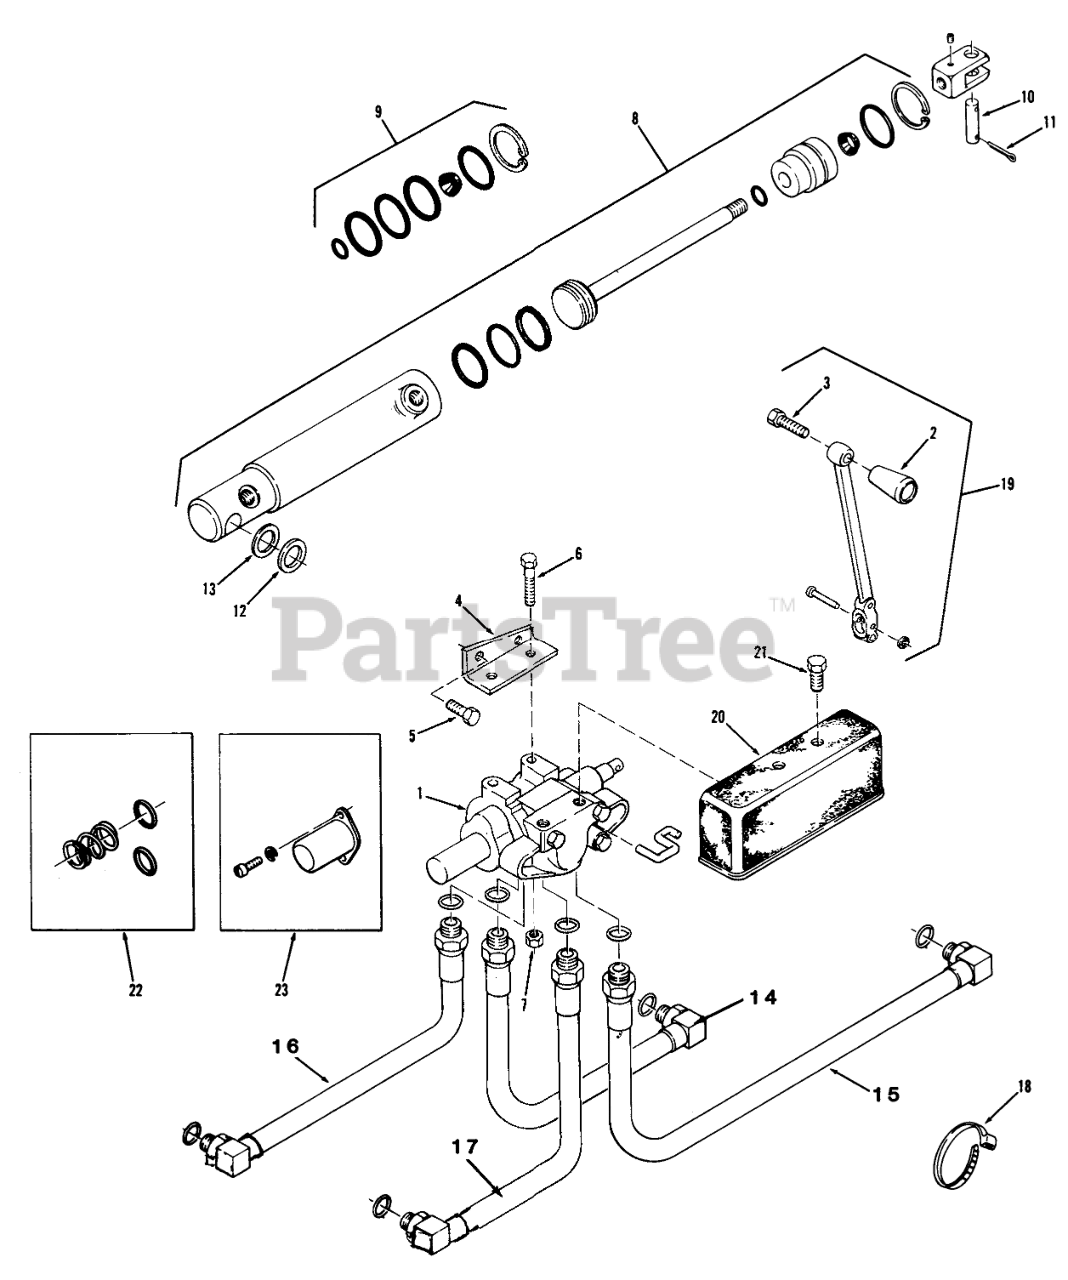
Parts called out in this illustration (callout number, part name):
1	Valve
3	SCREW
4	SUPPORT-VALVE
5	Bolt
6	Bolt 1/4-20 X 1 1/2
7	Nut
8	CYLINDER ASSY R
9	S/A O-RING&GASKET AS
10	PIN
12	Spacer
13	WASHER
14	16" Hose Assembly
15	HOSE HYDRAULIC 19"
16	ASSY-HYDRAULIC HOSE
17	HYD HOSE ASSY
18	PLASTIC TIE
19	Assy-Handle
20	Cover-Valve
21	Bolt
